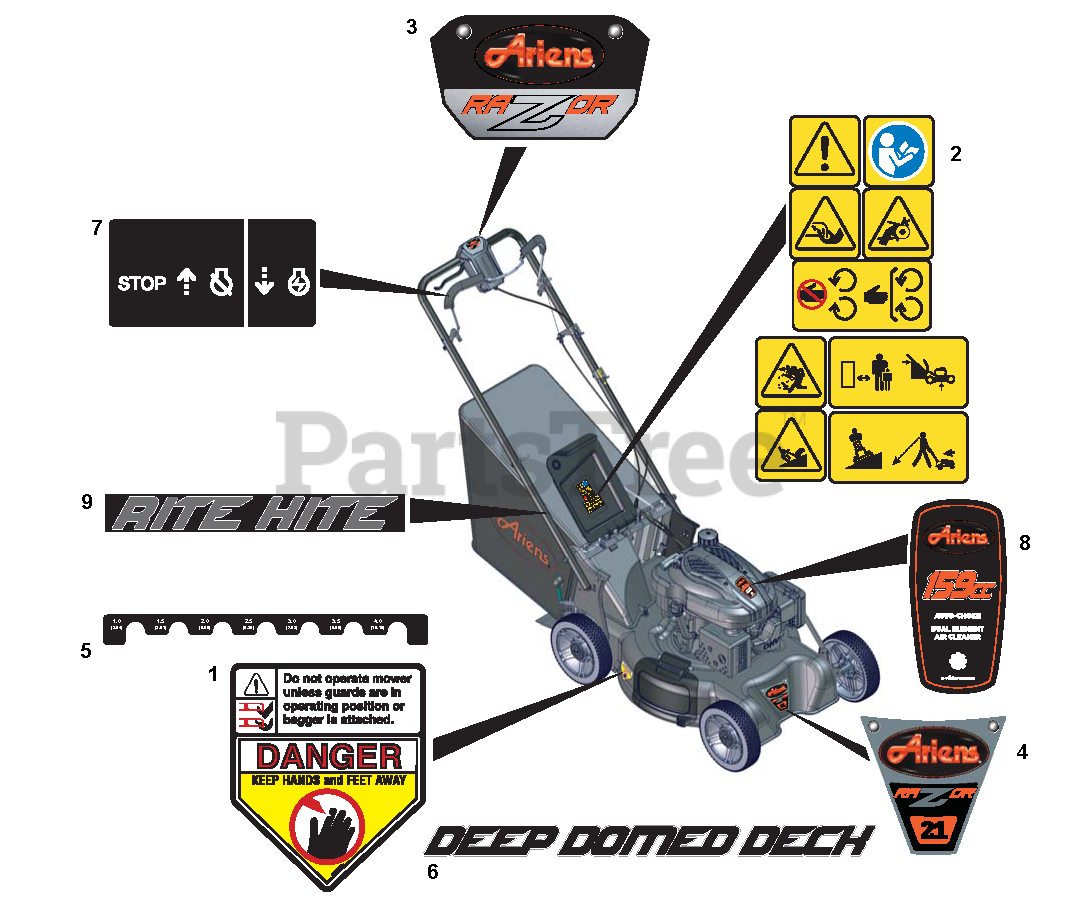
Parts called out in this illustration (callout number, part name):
1	DECAL, CPSC DANGER
2	DECAL,MAIN SAFETY_WAW LM
3	DECAL, ARIENS RAZOR - SMALL
4	DECAL, ARIENS RAZOR STYLE
5	DECAL, HOC
6	DECAL, DEEP DOME DECK
7	DECAL - ENGINE CONTROL
8	DECAL, ENGINE STYLE - ARIENS
9	DECAL, RITE HITE
